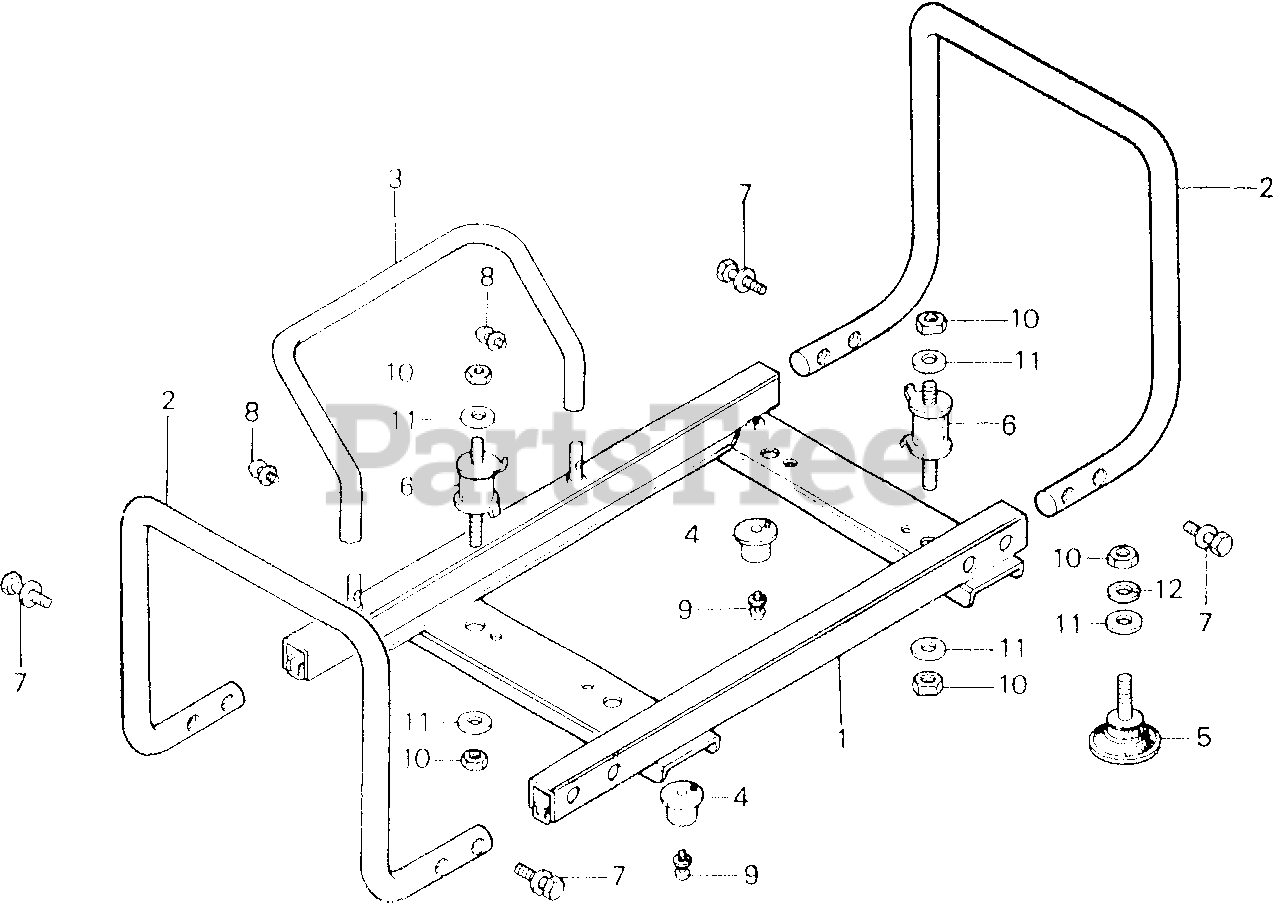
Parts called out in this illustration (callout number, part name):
1	BED, FRAME Use up to Frame SN 1382074.
2	FRAME, SIDE Use up to Frame SN 1382074.
3	PIPE, GUARD Use up to Frame SN 1382074.
4	RUBBER (LOWER) Use up to Frame SN 1382074.
5	RUBBER (LOWER)
6	RUBBER, ENGINE MOUNTING Use up to Frame SN 1382074.
7	BOLT-WASHER (8X20) Use up to Frame SN 1382074.
8	SCREW-WASHER (6X12) Use up to Frame SN 1382074.
9	SCREW-WASHER (5X10) Use up to Frame SN 1382074.
10	NUT, HEX. (8MM)
10	NUT, FLANGE (8MM)
11	WASHER, PLAIN (8MM)
12	WASHER, SPRING (8MM)
